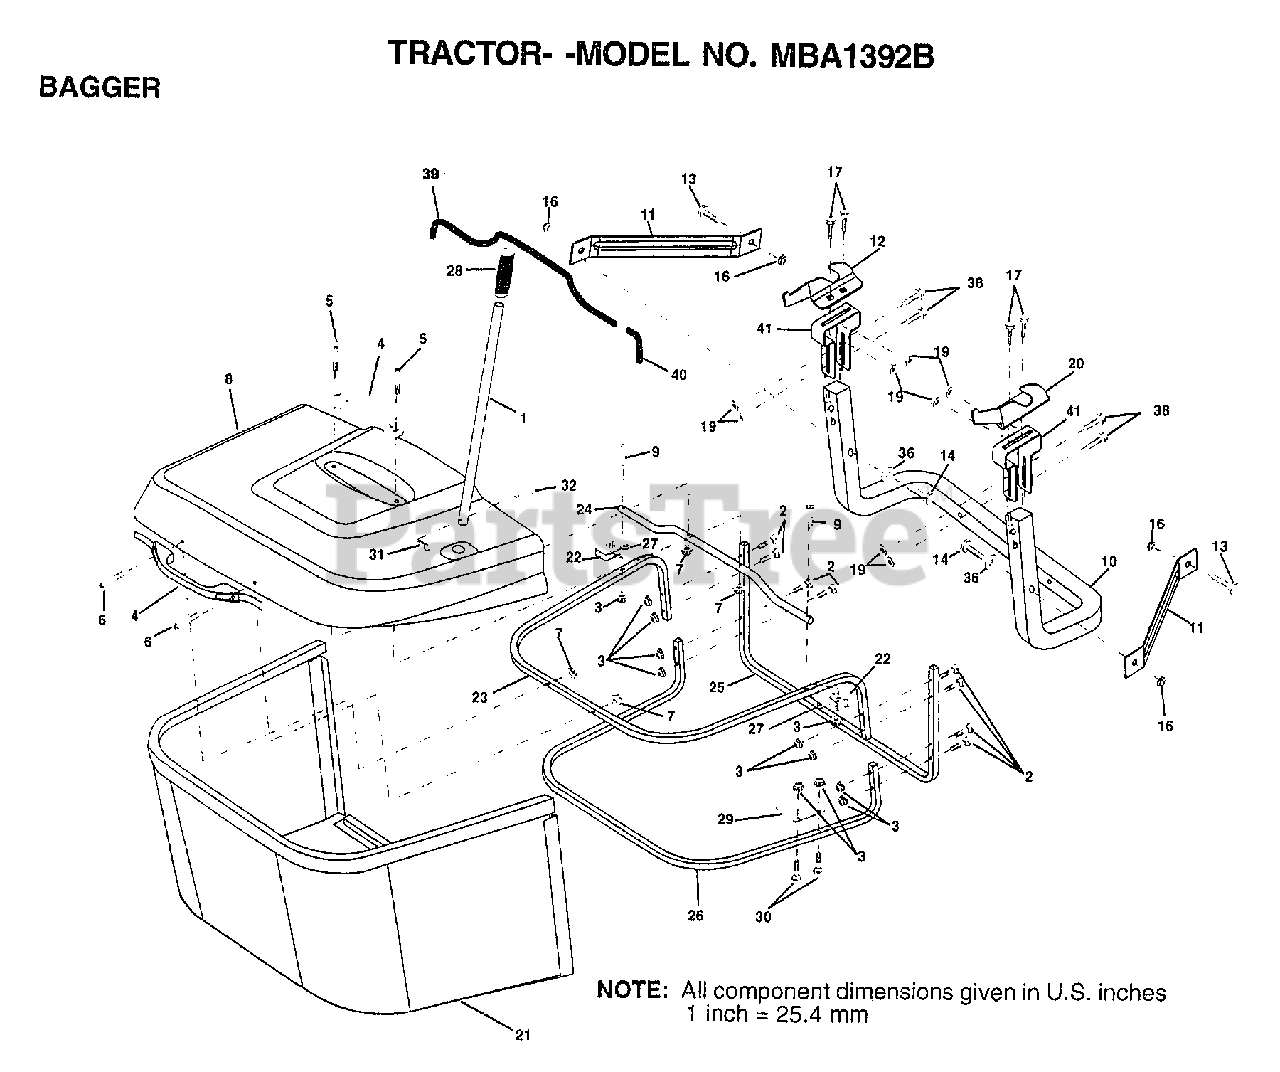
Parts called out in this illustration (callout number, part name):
1	TUBE.HDLE.BAG.CRD
2	BOLT.CARRIAGE.1/4-20X2.0
4	HANDLE BAGGER
5	"SCREW,PAN.HEAD"
7	NUT.WIZ.LOCK
8	COVER.BAG.PLASTIC.CRD
9	BOLT CARRIAGE
10	TUBE SUPPORT BAGGER CRD
11	BRKT.SUPT.UPPER.BAG.CRD
12	BRACKET HORIZ ADJ BGGR LH CRD
13	BOLT
14	BOLT.HEX.3/8-16X2-1/2
17	BOLT
19	NUT
20	BRACKET HORIZ ADJ BGGR RH CRD
21	BAG.ASM.CRD
22	BRKT.SIDE.BAG.CRD
23	TUBE.UPPER.BAG.CRD
24	TUBE.PIVOT.BAG.CRD
25	TUBE.FT.BAG.CRD
26	TUBE.LOWER.BAG.CRD.
27	BUSHING SNAP BAGGER CRD
28	GRIP.HANDLE.BLACK
29	PLATE.STOP.BAG.HDLE.CRD
30	BOLT.CARRIAGE
31	RETAINER M
32	RIVET.DRILL.1.75
38	BOLT.5/16-18X2.5
41	BRACKET VERT ADJ BAGGER CRD
